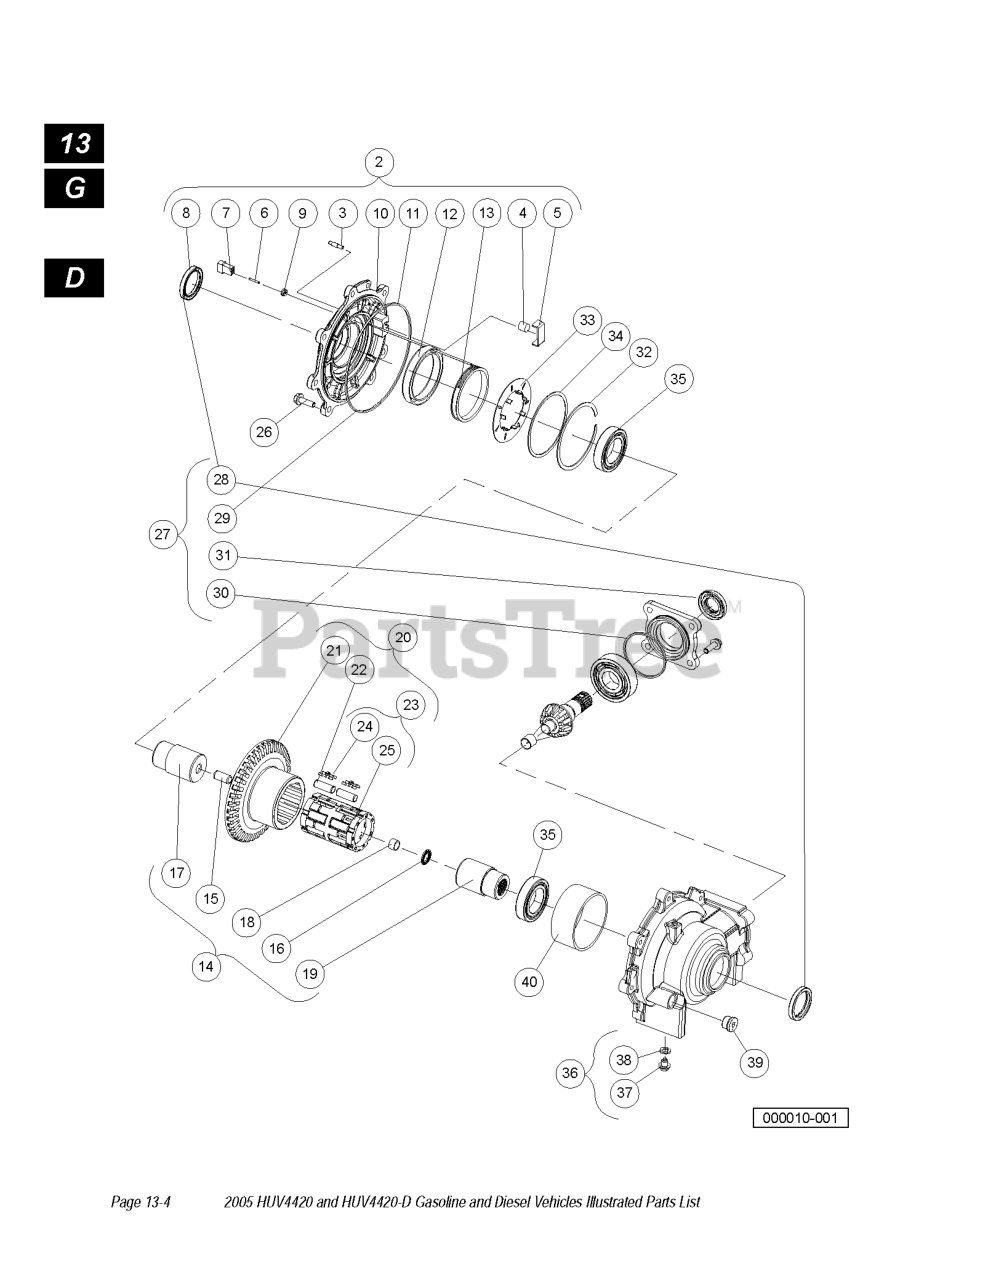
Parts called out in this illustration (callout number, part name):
1	DIFF, FRONT AUTO CCW 102371801
2	KIT, ASSY, OUTPUT COVER PLATE
3	SET SCREW, #10-24 UNC-3A, PATC
4	THRUST BUTTON
5	THRUST PLATE
14	KIT, ASSY, RACE OUTPUT HUB
15	DOWEL PIN, 1/2" DIA X 1" LG
16	BEARING, NRT, TC815
20	KIT, ASSY, CLUTCH
21	CLUTCH HSG/RING GEAR, MACHINED
22	KIT, ROLL
23	KIT, ASSY, ROLL CAGE
26	KIT, BOLT
27	KIT, MINOR REPAIR
32	RETAINING, RING INTERNAL
33	ARMATURE PLATE
34	SHIM, ARMATURE, PLATE
35	BEARING, DGBR, 6008-C3
36	KIT, ASSY, DRAIN PLUG
39	PLUG, OIL FILL
